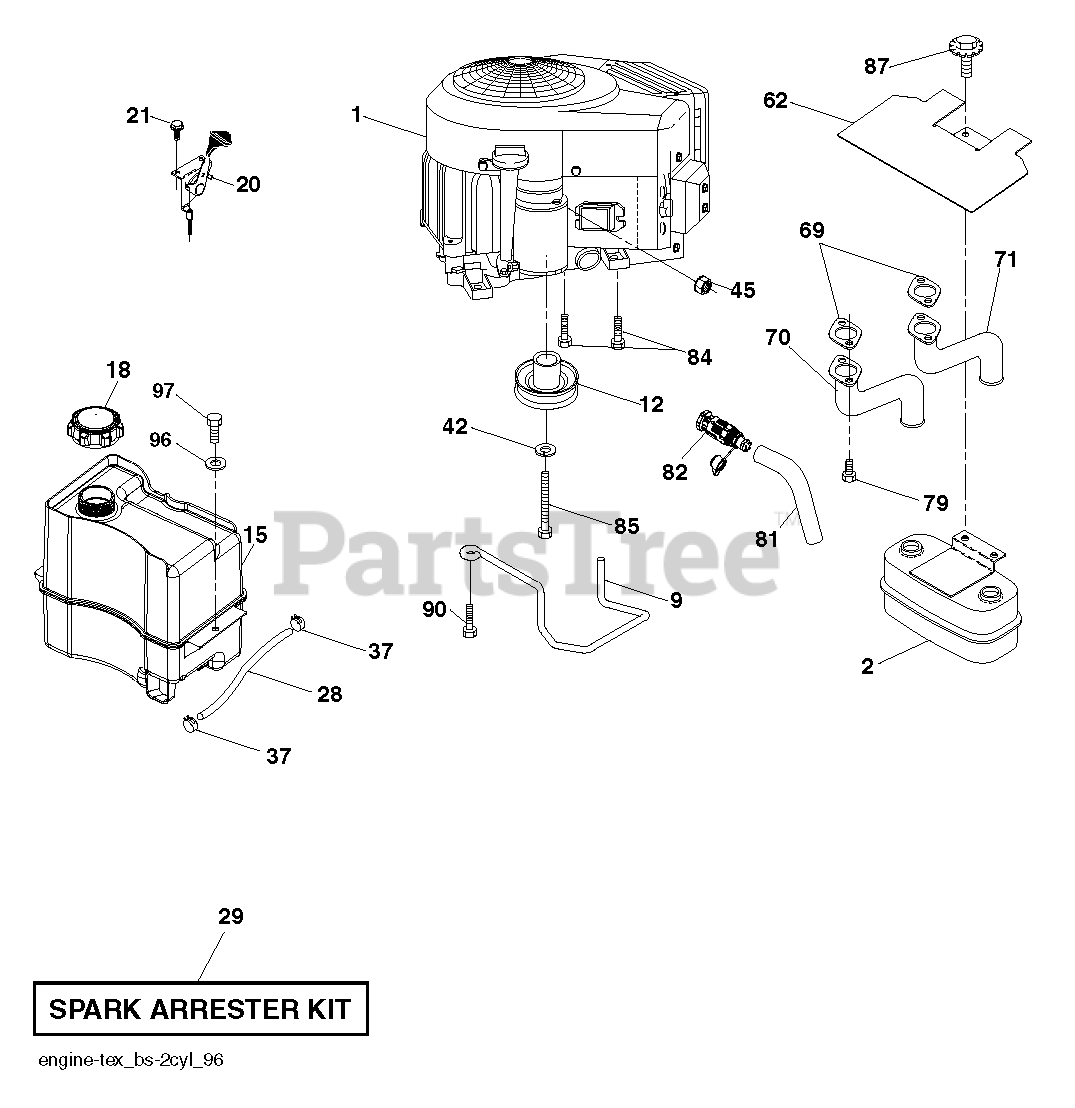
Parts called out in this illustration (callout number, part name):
2	MUFFLER.TWIN.CYL.LOW.TONE
9	KEEPER.BELT.ENGINE.4.2
12	PULLEY ENGINE
15	TANK.ASSEMBL.2.5GAL.NON-EPA
18	CAP ASM.FUEL.2.25"FR.
20	CONTROL.TH/CK.COBRA.B&S.TWN.
21	SCREW.#10 X 0.750.BOS (2 2)
28	LINE.FUEL.20
29	KIT.SPARK ARRESTOR(392390 B&S)
37	HOSE CLAMP
42	LOCKWASHER
45	NUT
62	SHIELD.HEAT.MUFFLER
69	GASKET.MUFFLER
70	RP.EXHAUST.TUBE.LH.BS/TWIN
71	RP.EXHAUST.TUBE.RH.BS/TWIN
79	SCREW.SOCKET.HEAD.5/16-18
81	TUBE, DRAIN OIL ASM.
82	VALUE.OIL.DRAIN
84	SCREW.3/8-16
85	BOLT HEX 7/16-20X4-1/4"
87	BOLT, 5/16-18 X 1 3/4
90	SCREW 3/8-16X1
97	SCREW HEXWSHR 1/4-20X3/4
